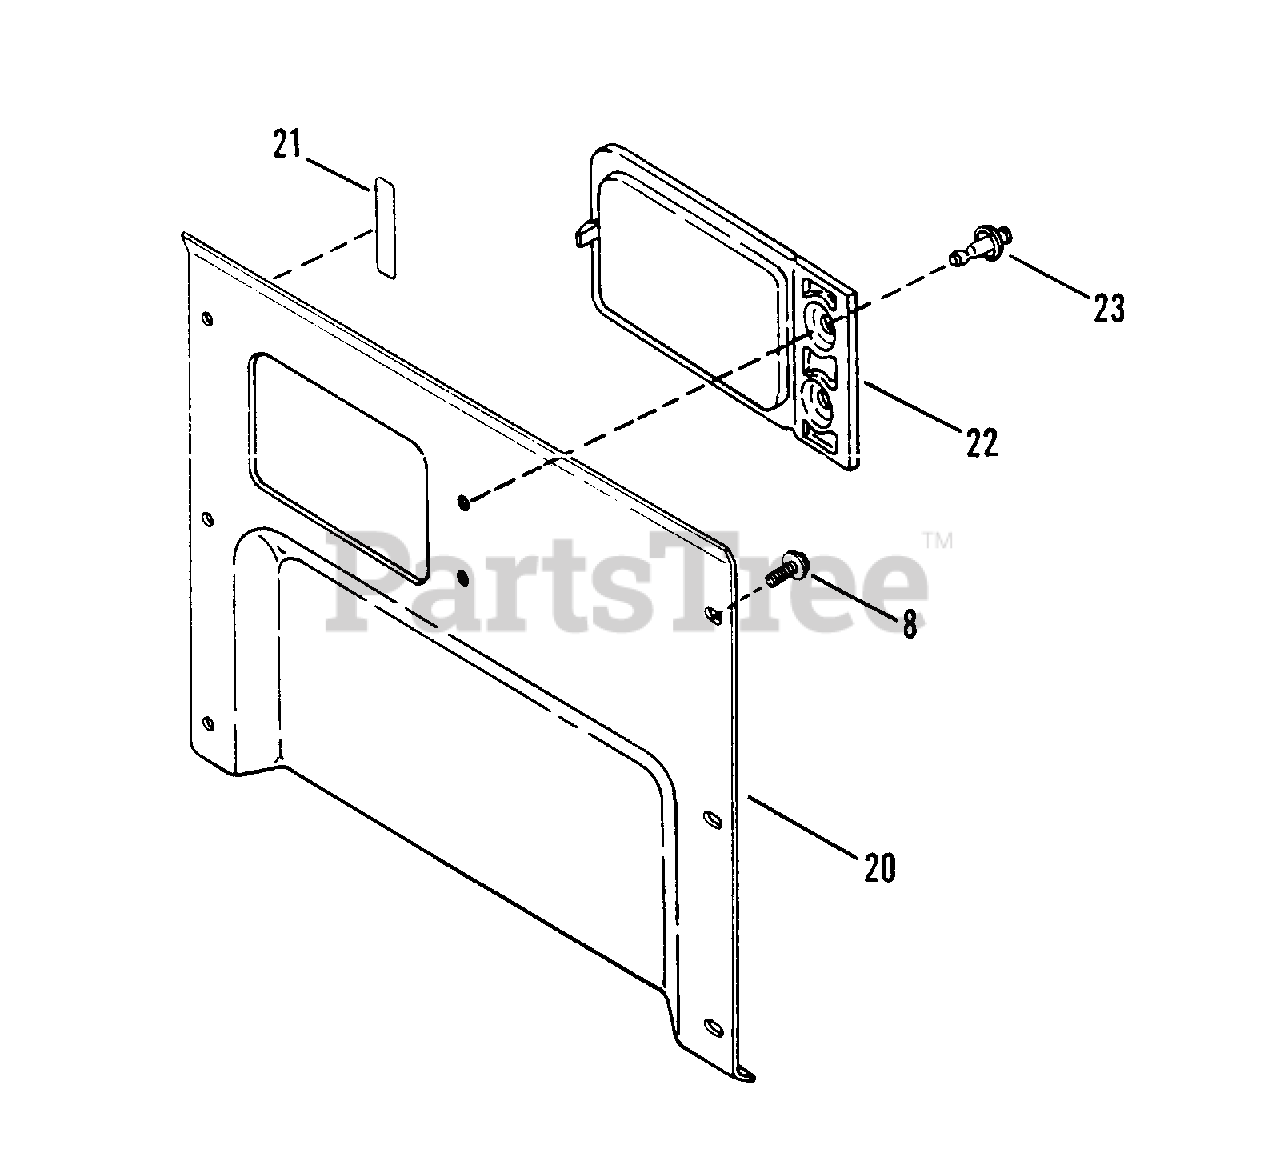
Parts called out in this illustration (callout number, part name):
8	SCREW, 5/16-18 x 5/8" Self-Tapping
20	COVER, Rear
21	DECAL, Roll
22	COVER, Transmission Oil Access (No longer available)
23	SCREW, Expansion
